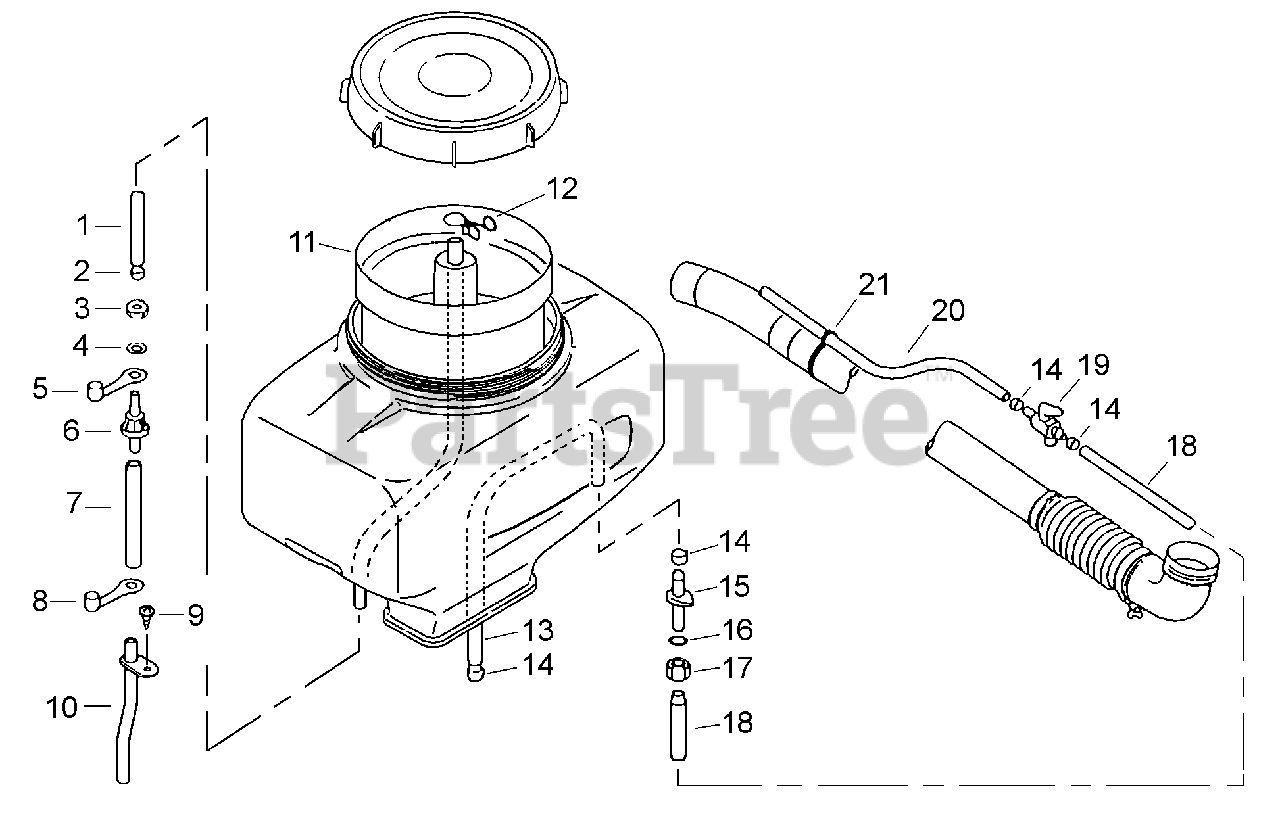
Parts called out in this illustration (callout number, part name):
1	TUBE, INNER PRESSURE 7×11×400BL
3	NUT - 12
4	WASHER - 12
6	CONNECTOR, PIPE
7	PIPE, VENT - OUTER
9	SCREW - 5X16
10	PIPE - VENT
12	CLIP
13	TUBE, DISCHARGE
15	CONNECTOR, PIPE
17	NUT, CONNECTOR
18	PIPE - 720
19	VALVE
20	PIPE - 650
